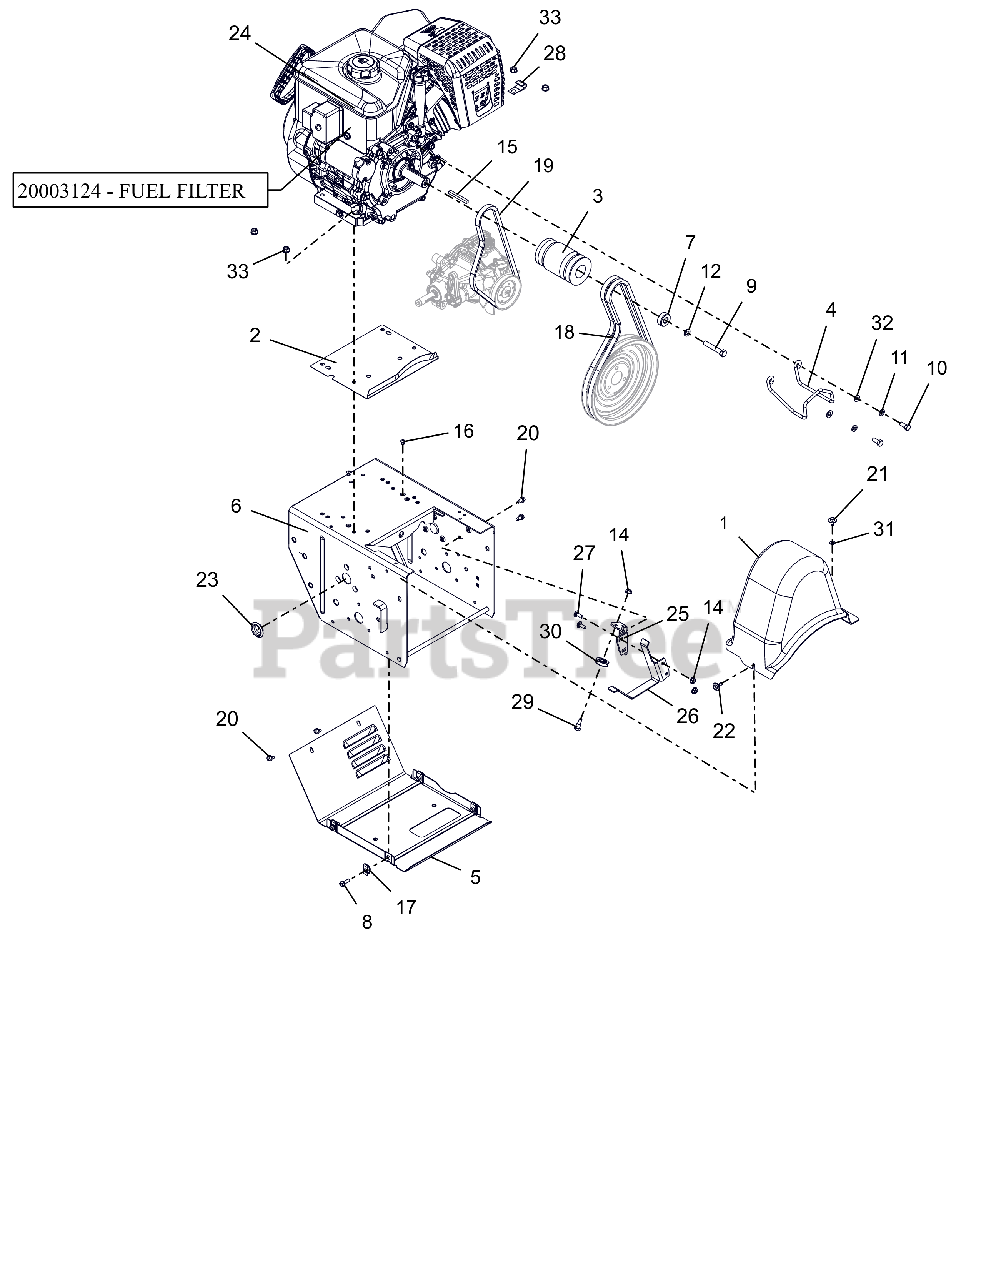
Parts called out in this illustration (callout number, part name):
1	COVER, BELT-LARGE
2	BAFFLE, WATER - LARGE BLOCK
3	SHEAVE, COMBO HYDRO WHEEL 4L
4	FINGER, BELT
5	COVER, BOTTOM - VENTILATED
6	FRAME, MAIN - PRO (WELDMENT)
7	BSHG-SPACER .47X1.25X.50
8	BLT, HWH .25-20X.75 G5 ZCC
9	BLT, HEX .38-24X2.25 G5 ZCC
10	BLT, HEX .31-24X.750 G5 ZCC
11	WSHR, LK-HVY .312X.097 ZCC
12	WSHR,LK-REG .375X.094 ZCC
14	NUT-LK-TOP-FLG .250-20 GF ZCC
15	KEY .25X.25X2.25
16	RVT, POP .1875 ZCC
17	NUT-RTNR .25-20X.56
18	V-BELT, HA-RAW EDGE (SET)
19	V-BELT, 4L-WRAPPED
20	SCR-TAP .25-20X.50 HWH ZCC
21	SCR, TAP .25-20X.50 LG HWH ZCC
22	SCR-TAP .25-20X.5 CAPTIVE
23	PLUG, HOLE - 1.125"
24	ENGINE, EFI 420 GEN 3 240V/60W
24	FILTER, FUEL - IN-LINE EFI
25	BRACKET, CLUTCH CABLE
26	FINGER, BELT - FLAT
27	BLT, RHSN .25-20X.750 G5 ZCC
28	J-CLAMP
29	BOLT, SHLDR -.375 X .375 X .25-20
30	PULLEY, CABLE
31	NUT-PUSH .25X.50 O.D.
32	WSHR,FLT .281X.625X.065 ZCC
33	NUT,LK-CTR-FLG .31-18 GF ZCC
